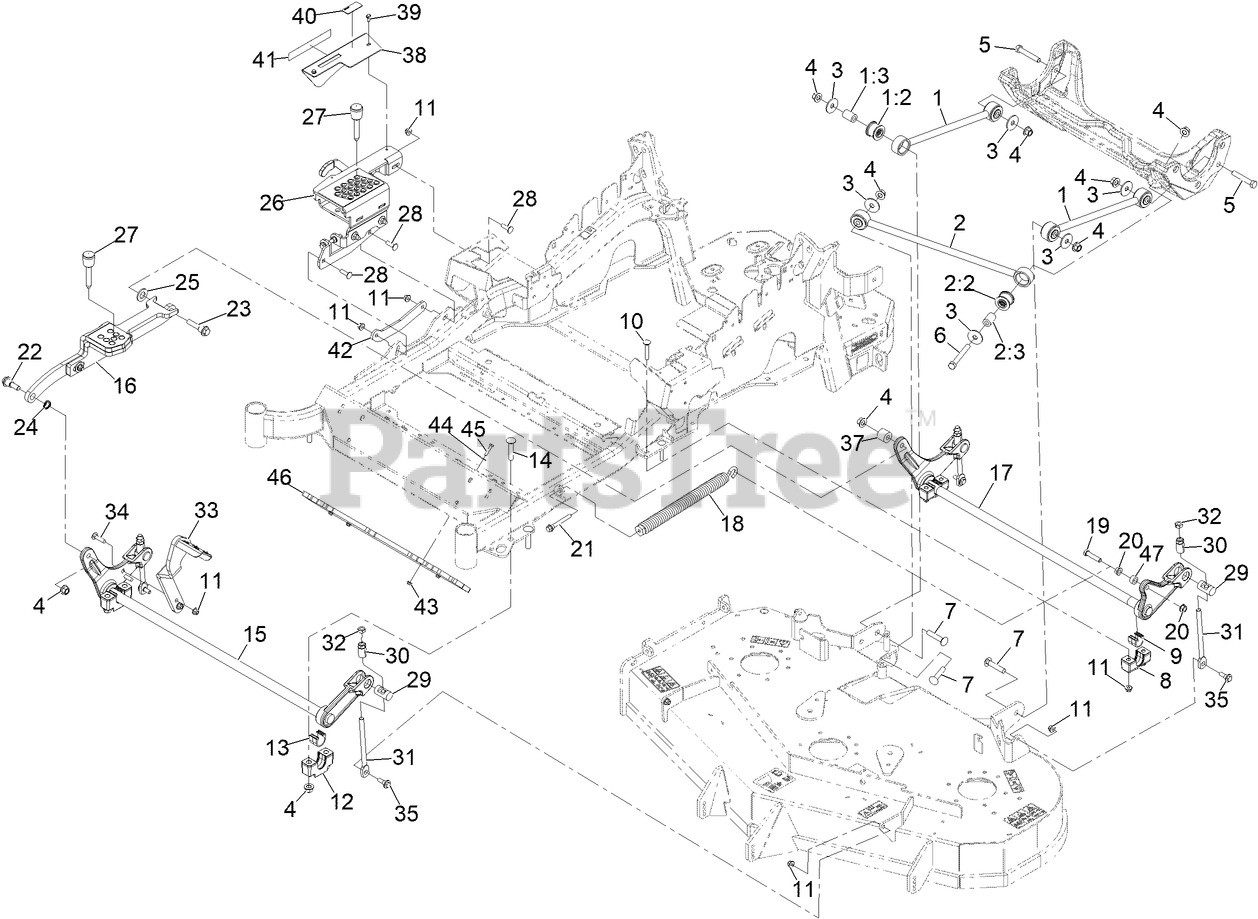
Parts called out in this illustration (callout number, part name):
1	DECK STRUT ASM
1:2	BUSHING-SUSPENSION, RUBBER
2	PANHARD ROD ASM
2:2	BUSHING-SUSPENSION, RUBBER
3	WASHER-THRUST
4	Nut-Lock 1/2-13
5	SCREW-HH
6	SCREW-HH
7	SCREW-CARR
8	SUPPORT-CROSS SHAFT, BEARING REAR
9	BEARING-CROSS SHAFT, REAR
10	Bolt-Carriage 3/8-16 X 2 1/4
11	NUT-HF, NI
12	SUPPORT-CROSS SHAFT, BEARING
13	BEARING-CROSS SHAFT, FRON
14	Bolt-Carriage 1/2-13 X 2 1/2 Spl Neck
15	Shaft- Deck Lift Front [black]
16	ASM- Link Deck Lift
17	Shaft- Deck Lift Rear [black]
18	SPRING-EXTENSION
19	SCREW-HH
21	BOLT-SHOULDER
22	SCREW-SHOULDER, HHF 1/2-13 X 1.12
23	SCREW-HHF, SHOULDER
24	WASHER-WAVE
25	WASHER-FLAT
26	ASM- Box HOC
27	ASM- HOC PIN
28	Bolt-Carriage 3/8-16 X 1 1/4
29	TRUNNION
30	ADJUSTER-LIFT, DECK
31	LINK-ADJUSTER, DECK LIFT
32	NUT-JAM
33	LEVER-FOOT
34	SCREW-CARR
35	SCREW-SHOULDER, HHF
37	Bushing- Link
38	ASM- Cover W/Decal
39	SCREW-HWH
40	Decal-Lever Lock, CE
41	DECAL-X-SERIES
42	Plate- Support
44	WASHER-FLAT
45	SCREW-HH
46	Weight-Toe Board
